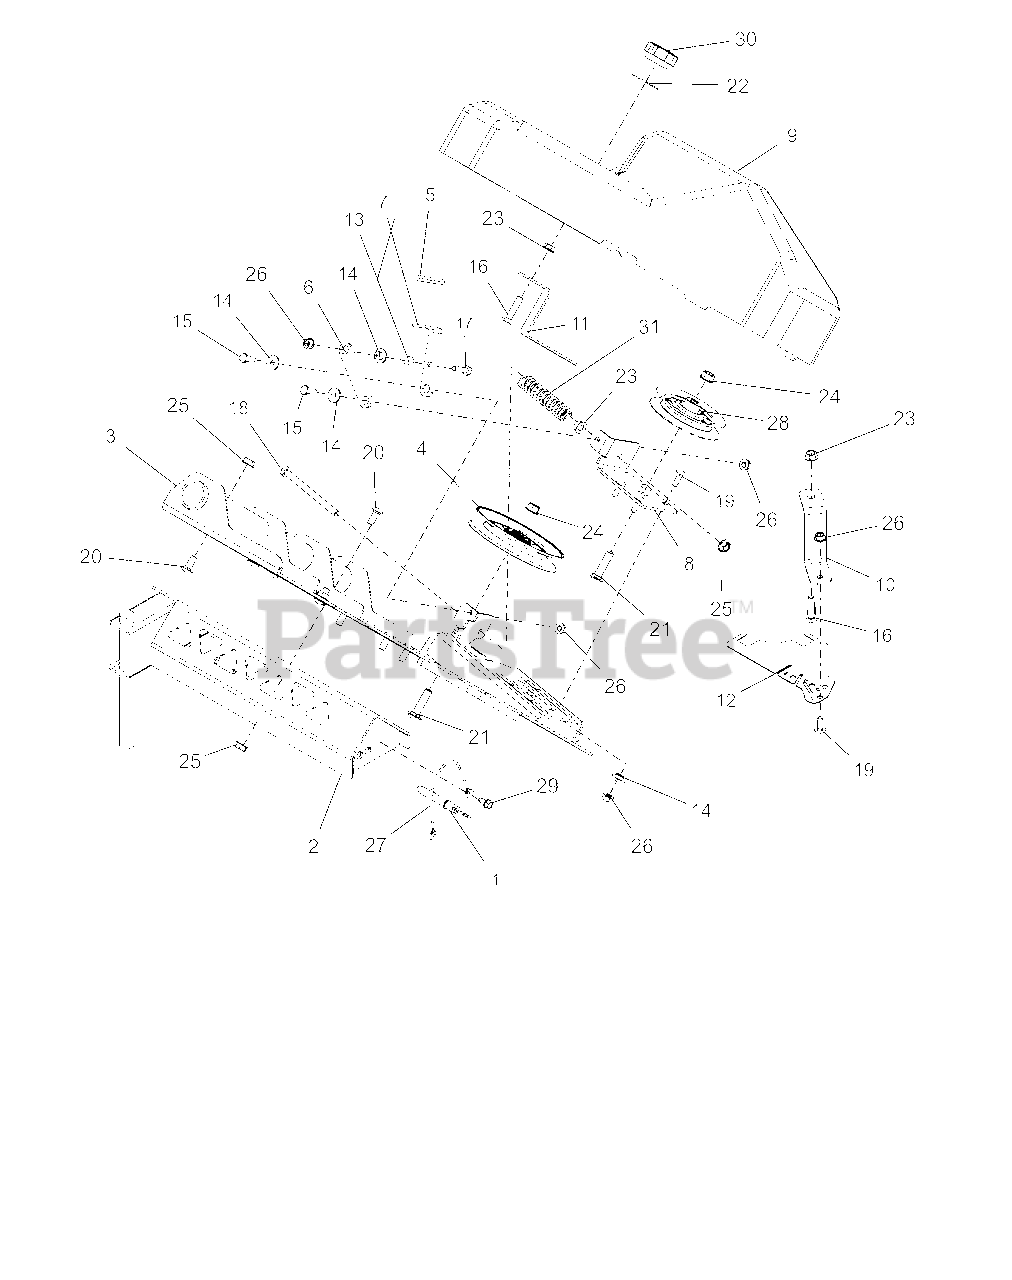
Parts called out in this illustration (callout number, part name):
1	PIN, SPRING BALL .375OD X 1.50
2	WLDMT, BLOWER MOUNT
3	WLDMT, BLOWER SPINDLE MNT (BLACK)
4	IDLER, V-5.00
5	GRIP, SEAT LEVER, GREY
6	LINK, TENSIONER
7	HANDLE, TENSIONER
8	PLT, TENSION PULLEY MOUNTING
9	COVER, BELT HD BLOWER
10	PLT, DECK COVER MNT
11	PLT, COVER MNT
12	PLT, TEMPLATE
13	BUSHING, .26 ID X .44 OD X .26
14	BSHG-FLG .265X.437X.250X.750
15	@BLT-HEX .25-20X.75 GR5 YWZC
16	@BLT-HEX .31-18X1.25 GR5 YWZC
17	@BLT-HEX .25-20X1.00 GR5 YWZC
18	@BLT-HEX .31-18X4.00 GR5 YWZC
19	@BLT-RDHDSQNK .25-20X.75 G5YZ
20	@BLT-RHDSSQNK .31-18X.75 G5YZ
21	@BLT-RHDSSQNK .38-16X1.50 G5YZ
22	WSHR-FL-STL .380X1.50X.062 YWZ
23	@NUT-SPNLK-FLG .312-18 YWZC
24	@NUT-LK-TOP-FLG .38-16 YWZC
25	@NUT-LK-TOP-FLG .31-18 YWZC
26	@NUT-LK-TOP-FLG .25-20 YWZC
27	CABLE, 12.0 LANYARD, NYLON
28	V-IDLER, 4.00X.38
29	SCR-TAP .25-20X.50 HWH TR YWZ
30	KNOB-CLAMPING, .312-18 NYLOC
31	SPRG, COMPRESSION
